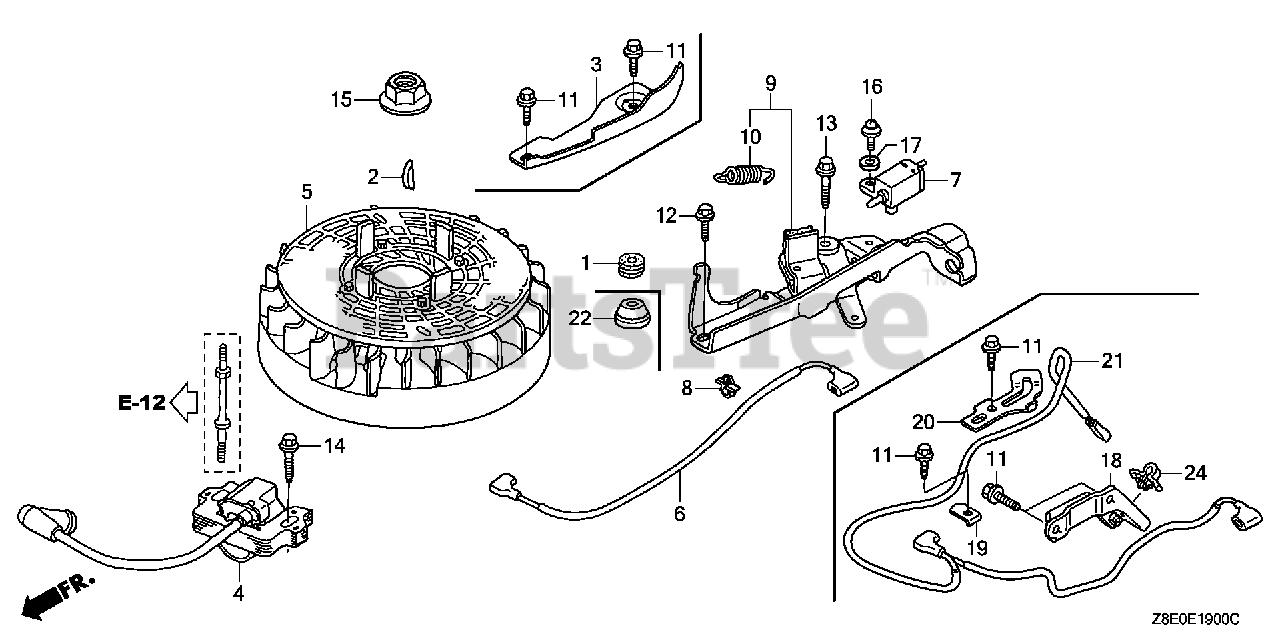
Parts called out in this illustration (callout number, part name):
2	KEY, SPECIAL WOODRUFF (25X18)
4	COIL ASSY., IGNITION (USE FOR F/W OF TEC) (TEC)
5	FLYWHEEL ASSY. (TEC) (USE FOR IGN. COIL OF TEC)
7	SWITCH ASSY., ENGINE STOP (N.C)
8	HOLDER, WIRE (FASTEX)
8	CLIP A, CABLE (3.8MM BLACK) (NIFCO)
9	BRAKE SUB-ASSY.
10	SPRING, BRAKE LEVER
11	BOLT, FLANGE (6X12) (CT200)
12	BOLT, FLANGE (6X14) (CT200)
13	BOLT, FLANGE (6X23) (CT200)
14	BOLT, FLANGE (6X23) (CT200)
15	NUT, FLANGE (14MM)
16	SCREW-WASHER (4X12)
17	WASHER, PLAIN (4MM)
18	CLAMP, STOP SWITCH WIRE
19	CLAMP, STOP SWITCH WIRE
20	CLAMP, WIRE
21	WIRE, STOP SWITCH
22	GROMMET, BRAKE PLATE
24	HOLDER, WIRE (FASTEX)
